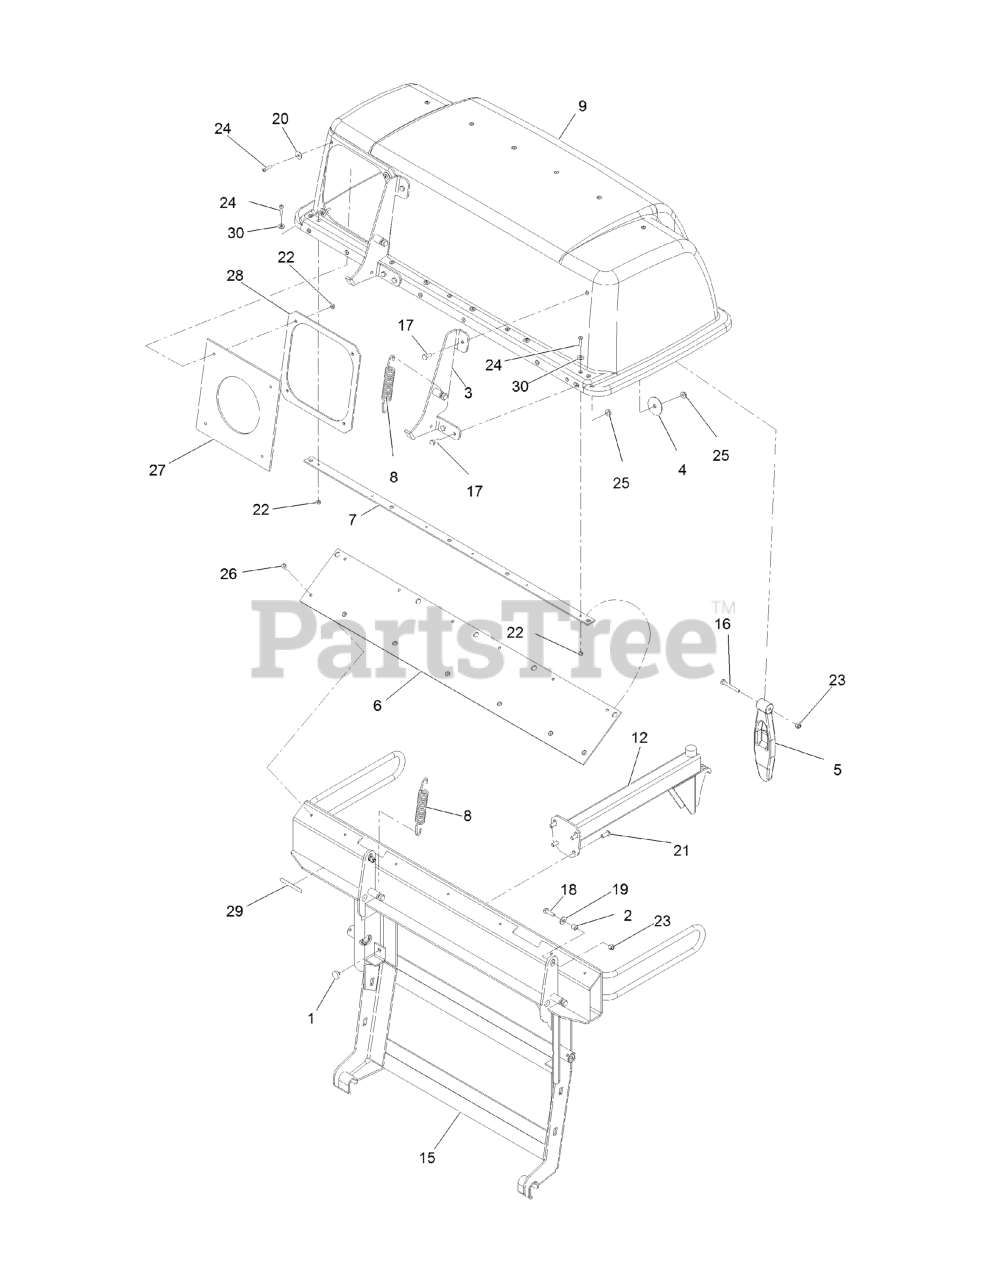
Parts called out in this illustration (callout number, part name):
3	HINGE ASM
7	PLATE-BACKING
8	SPRING-EXTENSION
9	ASM, HOOD
12	BAG SUPPORT ASM
15	FRAME-BAG, TWIN
16	SCREW-HH
17	SCREW-HH
18	SCREW-HH
19	WASHER-FLAT
20	WASHER-FLAT
21	SCREW-HSBH
22	NUT-LOCK, NI
23	NUT-LOCK, NI
24	SCREW-PPH
26	RIVET-BLIND
27	SEAL-CHUTE
28	CLAMP-SEAL
29	DECAL-WARNING
30	WASHER-FLAT
